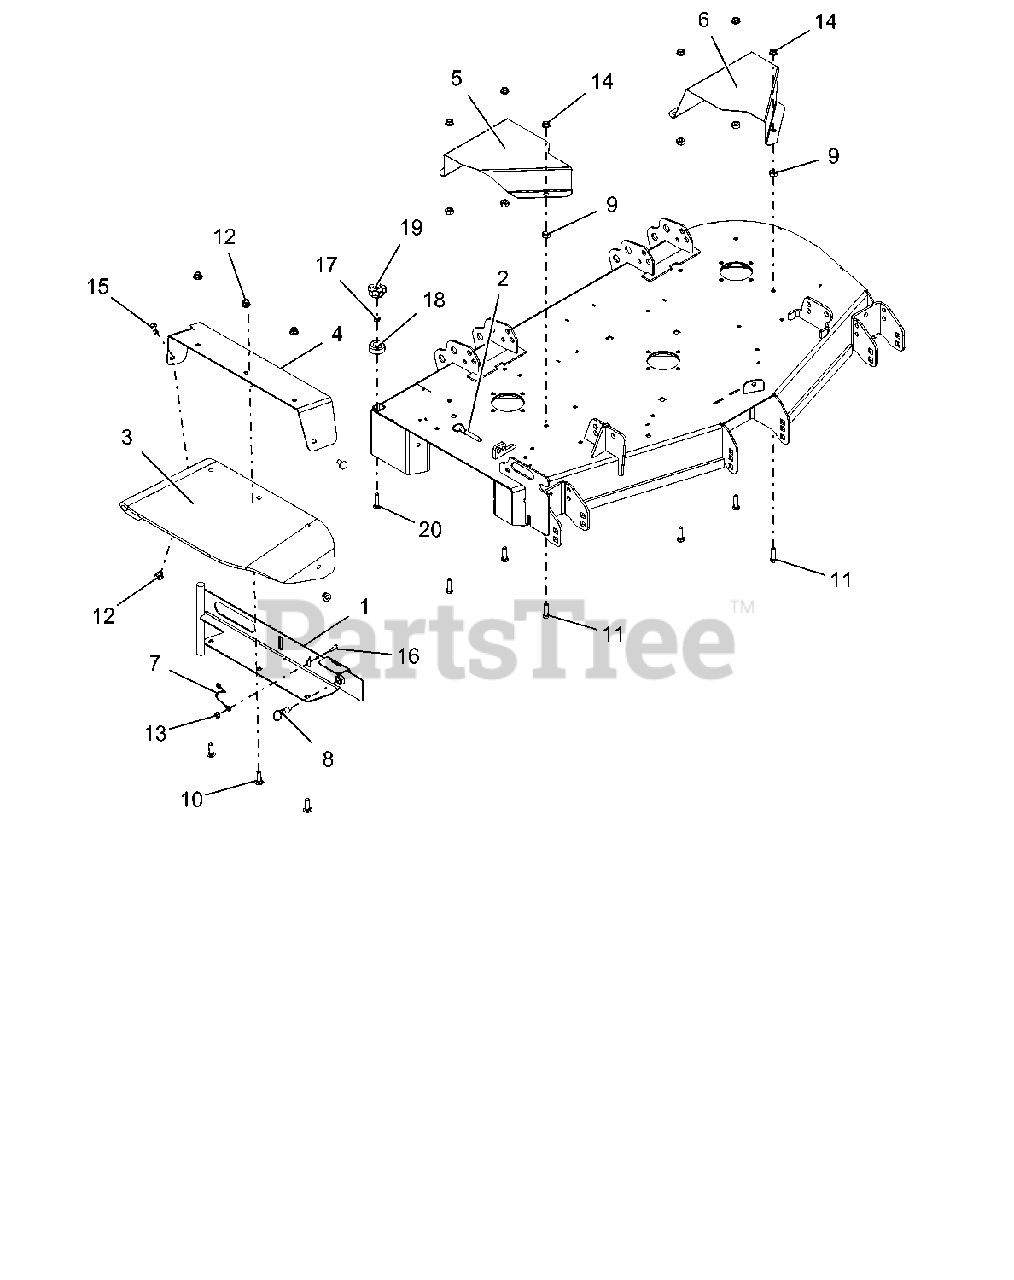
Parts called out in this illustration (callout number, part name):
1	WLDMT, DISCHARGE CHUTE 44"-48"
2	PIN, SPRING BALL .375OD X 1.50
3	CHUTE, RUBBER DISCHARGE
4	CHT SPPRT MTG BRKT W/SAFETY
5	GUARD, DECK 44"-52" RH
6	GUARD, DECK 44"-52" LH
7	CABLE, 6.0 LANYARD, NYLON
8	PULL PIN,.50-13THDX.310 PLNGR
9	NUT-HEAVY HEX .38-16 YWZC
10	@BLT-RDHDSQNK .38-16X1.25 G5YZ
11	@BLT-HEX .38-16X1.25 GR5 YWZC
12	@NUT-LK-NYL-FLG .38-16 YWZC
13	@NUT-LK-TOP-FLG .25-20 YWZC
14	@NUT-SPNLK-FLG .375-16 YWZC
15	@BLT-RDHDSQNK .38-16X1.00 G5YZ
16	@BLT-HEX .25-20X.75 GR5 YWZC
17	@NUT-LK-CTR .31-18 YWZC
18	BUMPER,RECESSED1.50X.63 W/.31
19	KNOB-CLAMPING, .312-18 NYLOC
20	@BLT-RDHDSQNK .31-18X1.50 G5YZ
